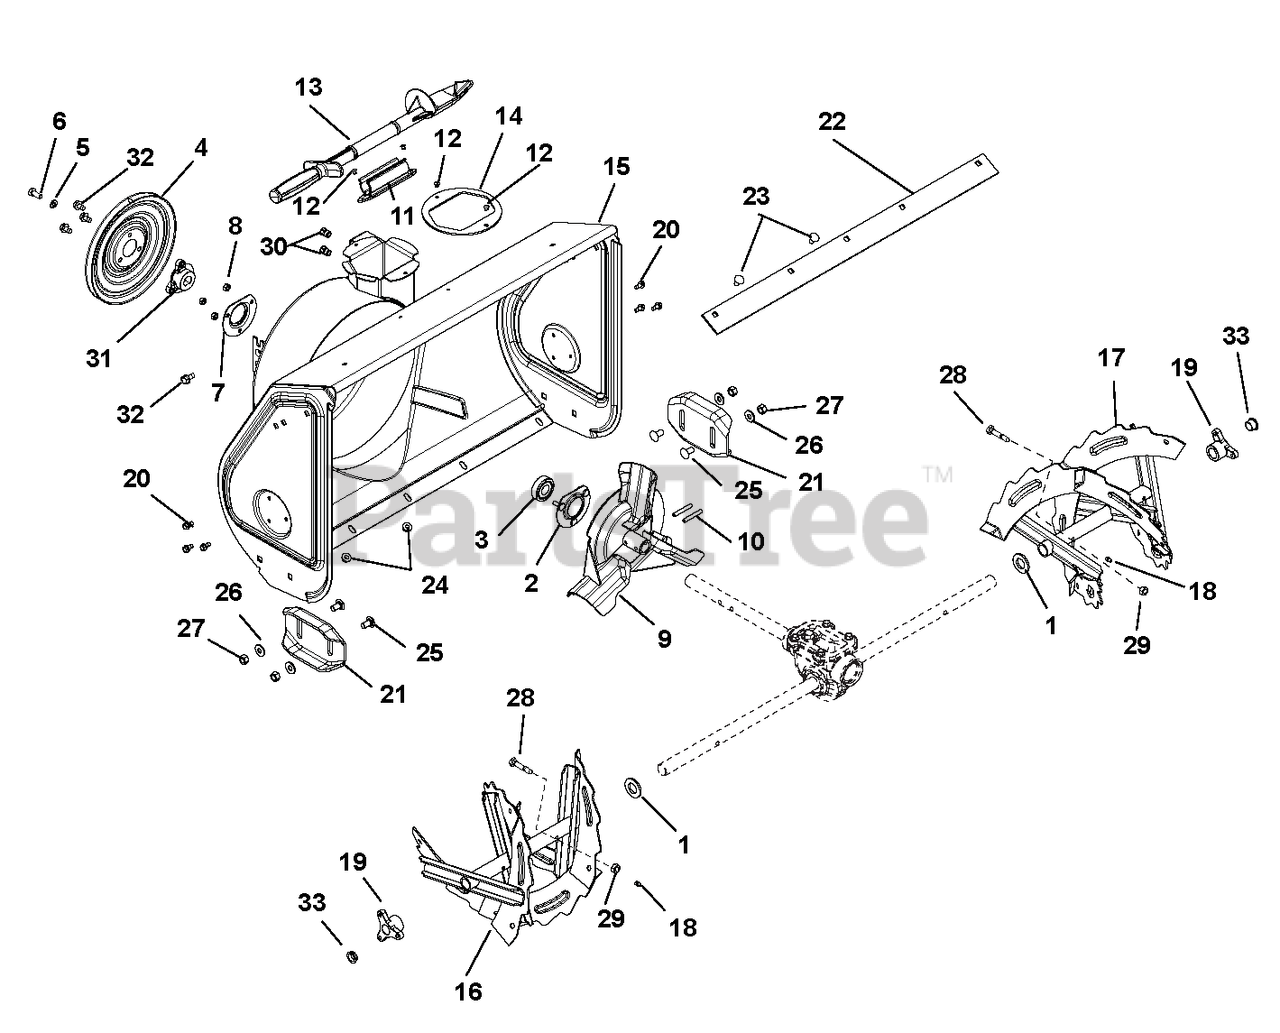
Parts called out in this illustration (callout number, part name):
1	@WSHR-FL-STL.812X1.50X.135YWZC
2	BEARING FLANGE
3	BRG-BALL .750X1.750X.50
4	PULLEY,SPIN FORM SINGLE GROOVE
5	WSHR-LK .312X.097 HVY YWZC
6	BLT-HEX .31-24X.75 YWZC GR5
7	BEARING FLANGE
8	@NUT-LK-CTR .25-20 YWZC
9	IMPELLER, COMPACT 12" 3-BLADE
10	PIN-ROLL .250X1.75
11	MOUNT, SNOW CLEAN OUT
12	RVT-POP .187 YZ
13	DEVICE, SNOW CLEAN OUT
14	BAFFLE, COMPACT DISCHARGE
15	BLOWER HOUSING, 24" HI ORANGE
16	RAKE, 24" RH, BLK SERR W/ZERK
17	RAKE, 24" LH, BLK SERR W/ZERK
18	ZERK,FITTING .25X.125 DRIVE IN
19	BUSHING, RAKE SHAFT .75"
20	SCR-TAP .25-20X.50 HWH TR YWZ
21	SKID SHOE, REVERSIBLE - ORANGE
22	SCRAPER BLADE, 24" COMPACT HI
23	BOLT, MODIFIED HEAD CARRIAGE
24	@NUT-LK-TOP-FLG .31-18 YWZC
25	@BLT-RHDSSQNK .38-16X.75 G5YZ
26	@WSHR-FL-STL.38X.875X.083 YWZC
27	@NUT-LK-CTR .38-16 YWZC
28	SHEAR BOLT WITH NUT
29	@NUT-LK-CTR .25-20 YWZC
30	NUT, THREADED INSERT .38-16
31	PULLEY HUB, BOLT-ON D-BORE .75
32	@SCR-TAP .31-18X.50 HWH TR YWZ
33	BSHG-FLG SPLIT NYLINER .75"ID
